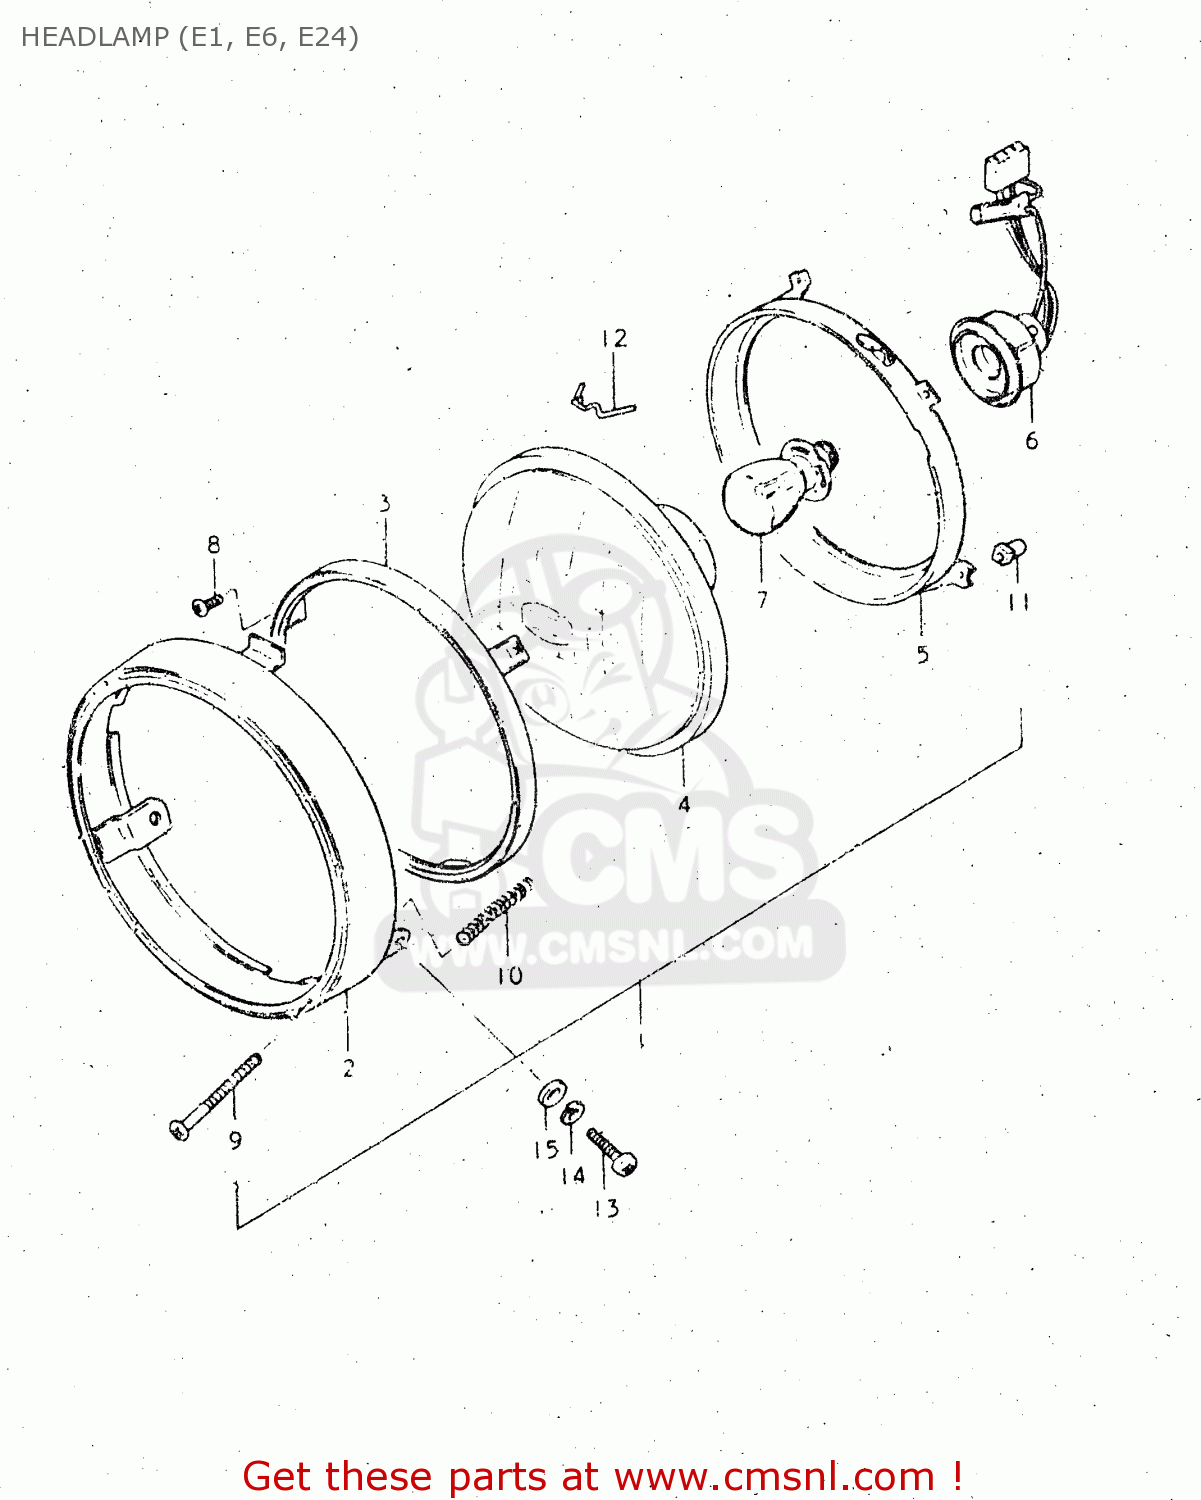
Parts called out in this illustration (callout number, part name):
1	HEADLAMP ASSY
2	RIM
3	RETAINER,HEADLAMP
4	UINT
5	RING, MOUNTING
6	SOCKET
7	BULB(6V,35/35W)
8	SCREW
9	SCREW,HEADLAMP ADJUST
10	SPRING,ADJUSTING
11	NUT,HEADLAMP ADJUSTER
12	SPRING,HEADLAMP UNIT
13	SCREW
14	LOCK WASHER
15	WASHER
